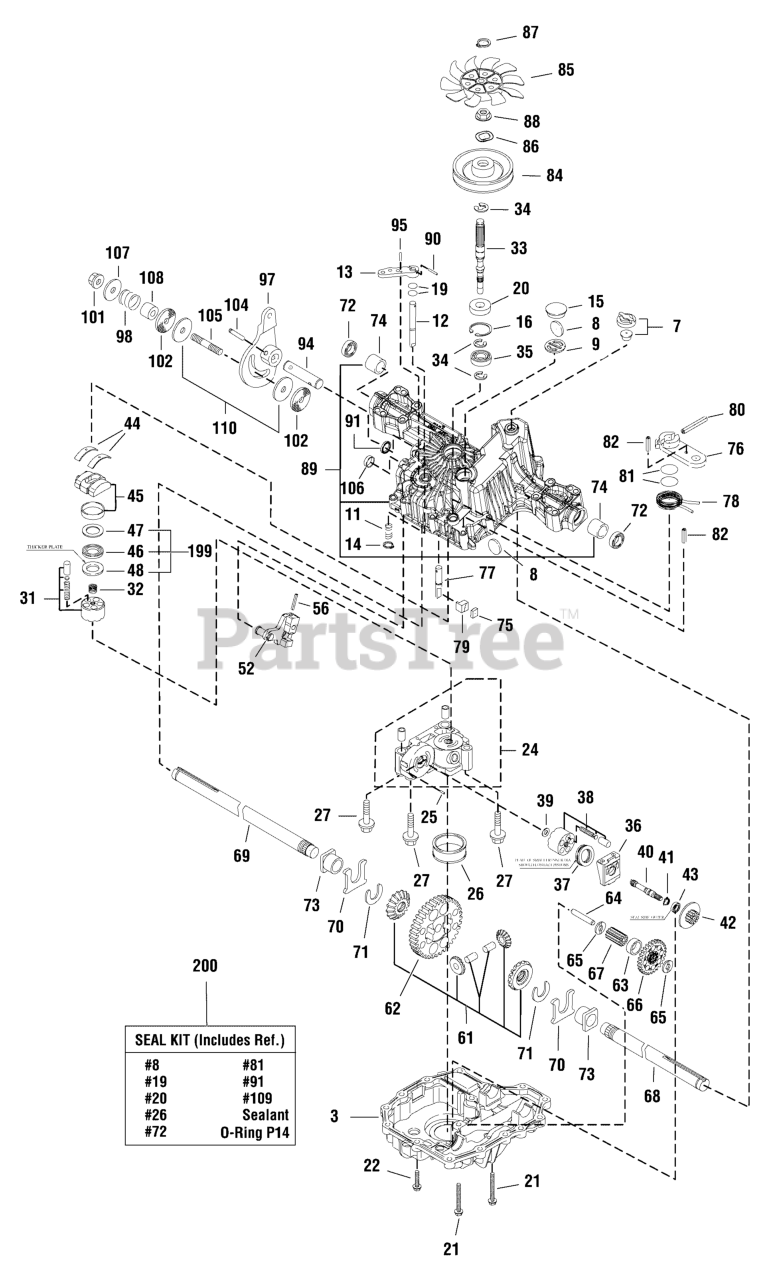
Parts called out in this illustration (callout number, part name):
3	*LOWER HOUSING
7	VENT VALVE
9	*HOLDER, Magnet
11	*SPRING
12	SHAFT, Bypass
13	LEVER
15	SEALING CAP
16	RING, Snap
19	O-RING, 1A P10A
20	SEAL
21	SCREW, Tapping
22	*SCREW, Tapping
24	*CENTER CASE
26	FILTER
31	CYLINDER BLOCK
32	SPRING, Pump
33	PUMP SHAFT
34	RING
38	CYLINDER BLOCK
40	SHAFT MOTOR
41	RING, Snap
42	MOTOR GEAR
43	BEARING
44	THRUST METAL
45	SWASH PLATE
47	THRUST PLATE
48	THRUST PLATE
52	*CONTROL ARM
56	SPRING PIN
61	DIFFERNIAL PINION
62	*FINAL GEAR
63	*COLLAR, Final
64	*REDUCTION SHAFT
66	REDUCTION GEAR
67	*FINAL PINION
68	AXLE SHAFT
69	AXLE SHAFT R
70	THRUST WASHER
72	SEAL
74	*BUSHING
75	SHOE, Brake
76	ARM, Brake
77	*SHAFT, Brake
78	RETURN SPRING
79	ACTUATOR, Brake
81	O RING
82	PIN, Spring
85	FAN
86	LOCKWASHER
87	SNAP RING
88	*COLLAR, Spline
89	*UPPER HOUSING
90	SPRING PIN
91	OIL SEAL
94	*CONTROL SHAFT
97	*CONTROL LEVER
98	SPRING, Friction
99	WASHER, Seal
100	*SCREW, Cap
101	LOCK NUT
104	PIN, Roll
105	STUD BOLT
110	FRICTION PLATE
199	*BEARING
200	*K46 SEAL KIT (All Models)
201	*Repair Kit
